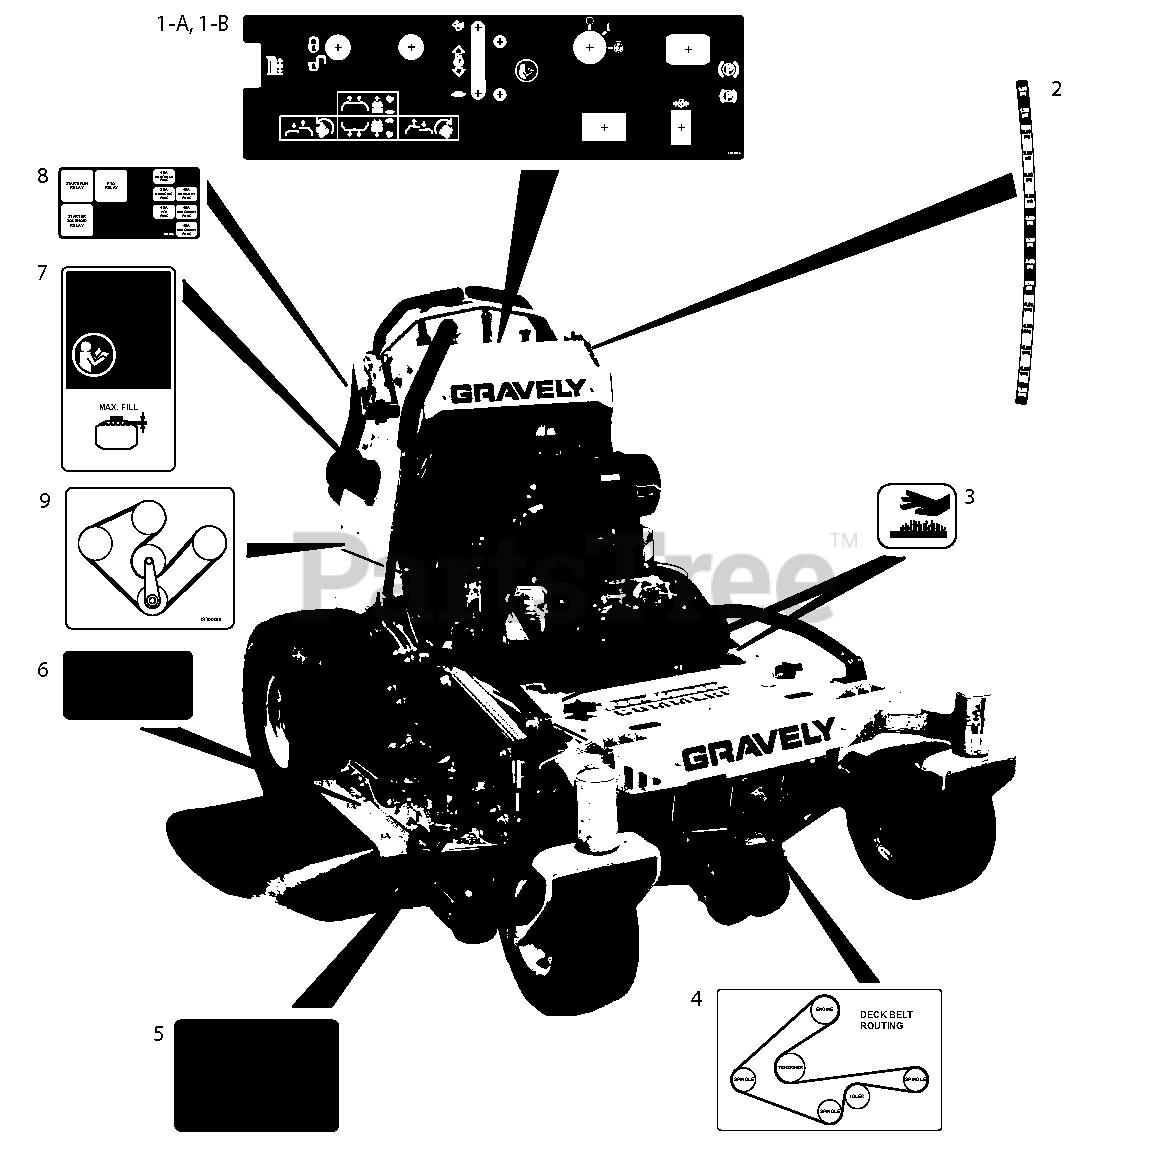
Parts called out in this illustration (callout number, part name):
1-A	DECAL, CONTROL PANEL (994111,112,114,117,118)
1-B	DECAL, CONTROL PANEL EFI (994113,115)
2	DECAL, PRO-STANCE HOC
3	DECAL, HOT SURFACE
4	DECAL, BELT ROUTING - DECK
5	DECAL, SAFETY MOWER DECK
6	DECAL, SAFETY DECK GUARDING
7	DECAL, FUEL, WARNING
8	DECAL, FUSE BLOCK
9	DCAL, PRO-STANCE HYD BELT
